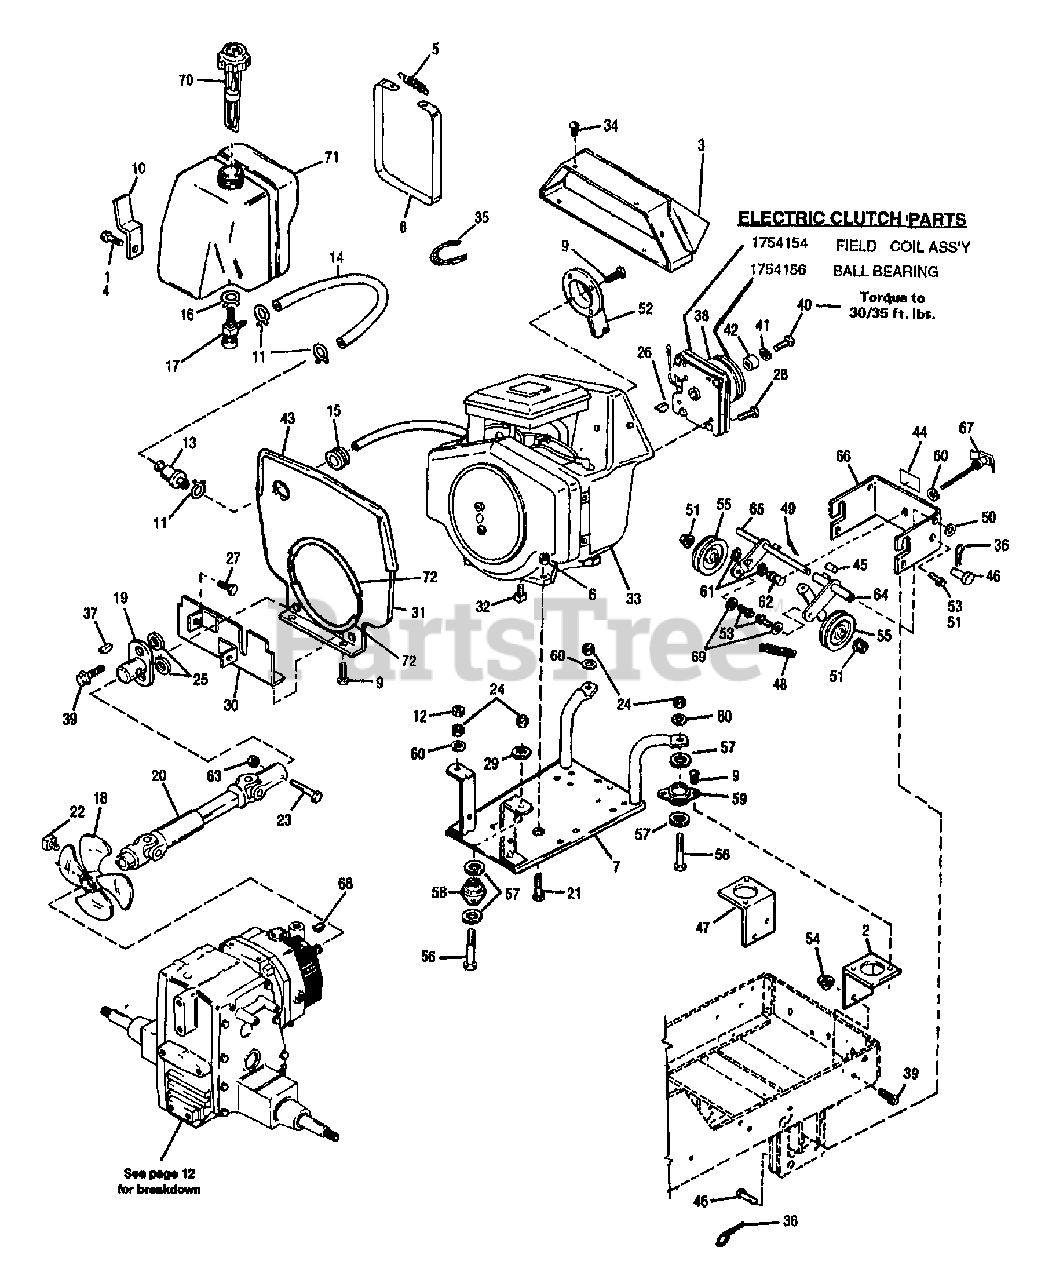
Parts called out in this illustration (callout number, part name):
1	SCR-HFLK 1/4-20X.75 G5 ZP
2	SUPT-ENG RH FRONT
3	DEFL-HEAT SHIELD
4	NUT-HF/LK 1/4-20 ZP
5	SPRING-EXTENSION
6	NUT-HFLK 5/16-18 ZP
7	SUPPORT-ENGINE
10	RETAINER-TANK
11	CLAMP-HOSE
12	NUT-HEX/JAM 3/8-16 ZP
13	FILTER-FUEL
14	LINE-FUEL
15	BUSHING
16	CLAMP-HOSE
17	VALVE-SHUT OFF
18	FAN
19	EXTENSION-ENGINE
20	ASSM-DRIVESHAFT
21	SCR-HFLK 5/16-18X1.25 ZP
22	SCR-SQ HD SET 5/16X3/4
23	SCR-HH 1/4-20X2.0 G5 ZP
24	NUT-LOCK 3/8-16
25	WASHER-FLAT 3/8 SAE
26	KEY-.25 SQ X.75
27	SCR-HFLK 5/16-18X.50 ZP
28	SCR-HH 3/8-16X.50
29	WASHER-LK .375 PYRAMIDAL
30	SHIELD-GRASS
31	SHIELD-HEAT
32	PLUG-SQ HEAD 1/4-18 NPT
33	ENGINE, 16HP, BRIGGS & STRATTON 402447
34	SCR-FL SELF TAP
35	CABLE TIE
36	PIN-HITCH .125X2.56 ZP
37	KEY-WOODRUFF .25X.875
38	CLUTCH/BRAKE ELEC
40	SCR-HH 3/8-24X1.0 G5 ZP
41	WASHER-LK .375 @ DEPL
42	CLUTCH-RETAINER
43	GASKET-HEAT SHIELD 32"
44	DECAL-BELT ADJUSTMENT
45	CAP-INDICATOR
46	PIN-CLEVIS .5X1.06 ZP
47	SUPPORT-ENGINE
49	PIN-COTTER .120X1.00 ZP
50	WASHER-1.305X.649X.098 ZP
51	NUT-HFLK 3/8-16 ZP
52	ASSM-EXHAUST
53	SCR-HFLK 3/8-16X1.75 G5ZP
54	NUT-HFLK 3/8-16 ZP
55	PULLEY-IDLER
56	SCR-HH 3/8-16X2.25 G5 ZP
57	WASHER
58	MOUNT-REAR
59	MOUNT-FRONT
60	WASHER-FLAT 3/8 SAE
61	RING-RETAIN EXT .707 ID
62	PIVOT
63	NUT-HT LK 1/4-20
64	ASSM-IDLER ARM
65	ASSM-IDLER ARM
66	SUPPORT-IDLER
67	KNOB-ADJUSTING
68	KEY-WOODRUFF
69	WASHER-.986X.437X.083 ZP
70	CAP-GAS
71	TANK-FUEL
72	SEAL-HEAT SHIELD
